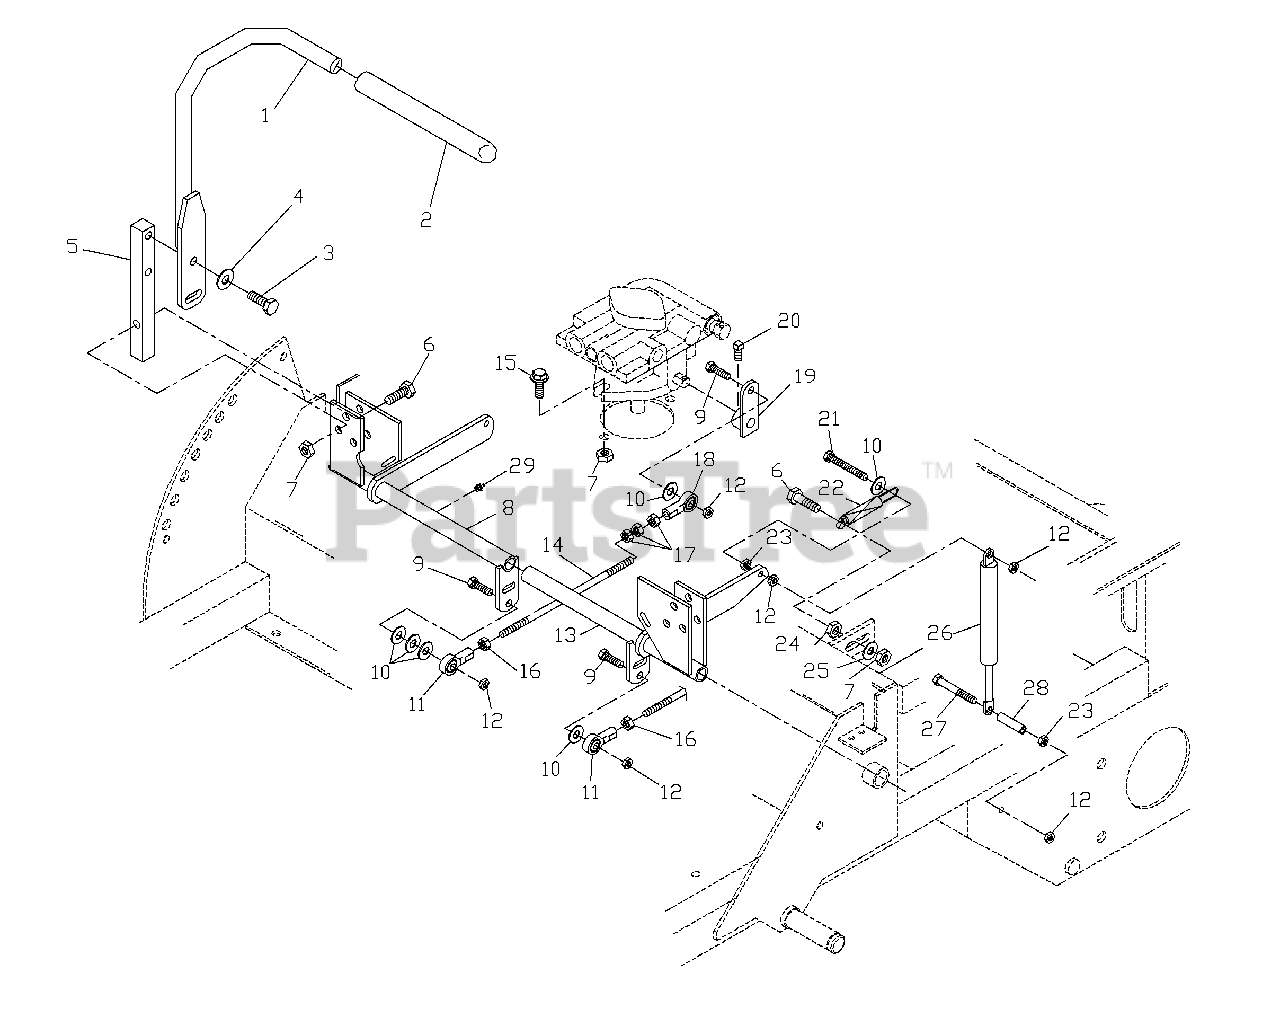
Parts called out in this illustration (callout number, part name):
1	CONTROL LEVER WLDMT
3	HCS 3/8C X 1
4	3/8 DISC SPRING WASHER
5	CONTROL ARM
6	HCS 3/8C X 1 1/2
7	NUT 3/8C CENTERLOCK
8	CONTROL WELDMENT, RIGHT
9	HCS 5/16C X 1 1/4
10	WASHER 5/16 FLAT
11	BALL JOINT, LEFT HANDED
12	NUT 5/16C CENTERLOCK
13	CONTROL WELDMENT, LEFT
14	PUMP CONTROL LINK
15	HCS 3/8C X 1 SERRATED HEAD
16	NUT 5/16F LEFTHAND
18	BALL JOINT, RIGHTHAND
19	CONTROL ARM, PUMP
20	5/16C X 5/8 SQ. HEAD
21	TAPBOLT 5/16C X 2 1/4
23	5/16C WHIZ NUT
24	3/8C WHIZ NUT
25	WASHER 3/8 FLAT
27	HCS 5/16C X 2 3/4 GRADE 8
29	ZERK
